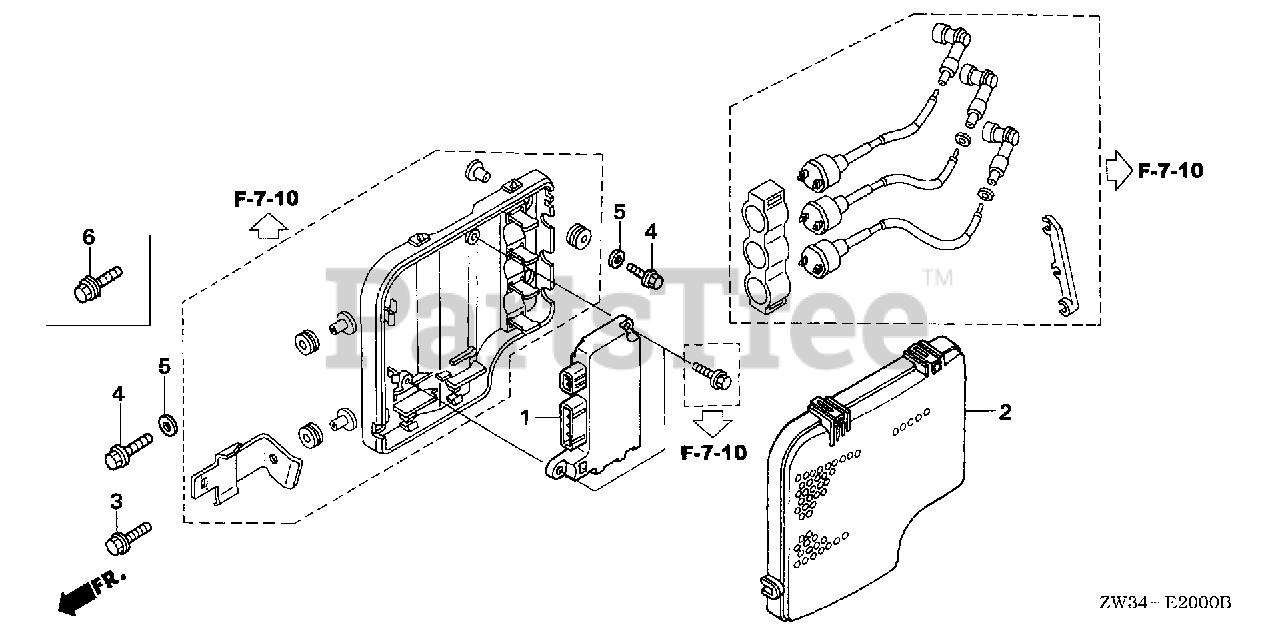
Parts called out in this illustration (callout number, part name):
2	COVER, IGNITION CONTROL MODULE (CDI)
3	BOLT, FLANGE (6X28) (CT200)
6	BOLT-WASHER (6X27) (CT200)
